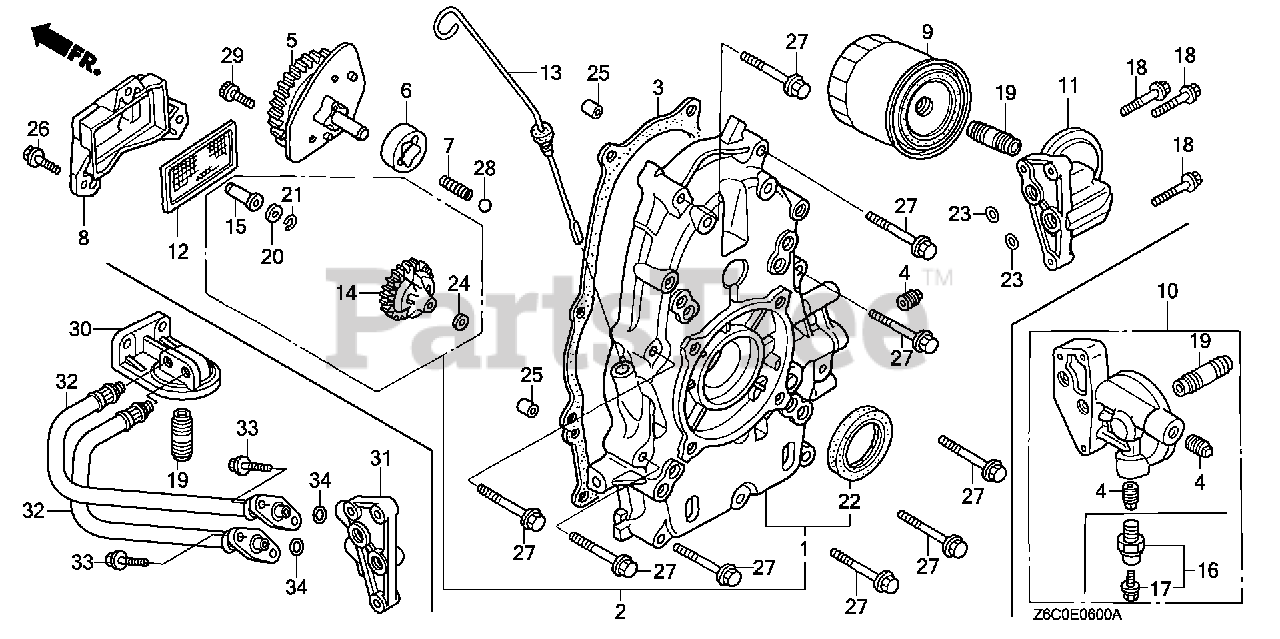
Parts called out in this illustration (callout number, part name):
2	COVER ASSY., CRANKCASE
3	GASKET, CASE COVER
4	BOLT, SEALING
5	COVER ASSY., OIL PUMP (THREE BOLTS)
6	ROTOR, OIL PUMP (OUTER)
7	SPRING, RELIEF VALVE
8	COVER, OIL FILTER
9	FILTER, OIL
9	FILTER, OIL (Honda Code 6836290). (SOLD INDIVIDUALLY)
11	BASE, OIL FILTER
12	SCREEN, OIL FILTER
13	DIPSTICK, OIL
14	GOVERNOR ASSY.
15	SLIDER, GOVERNOR
18	BOLT, FLANGE (6X28) (CT200) Use up to Engine SN 1530314.
19	HOLDER, OIL FILTER
20	WASHER (6X16)
21	CLIP, GOVERNOR HOLDER
22	OIL SEAL (38X58X9)
23	O-RING (11.8X2.4)
24	WASHER, PLAIN (6MM)
25	PIN A, DOWEL (8X14)
26	BOLT, FLANGE (6X20)
27	BOLT, FLANGE (8X50)
28	BALL, STEEL (#12) (3/8)
29	BOLT, SOCKET (6X16)
